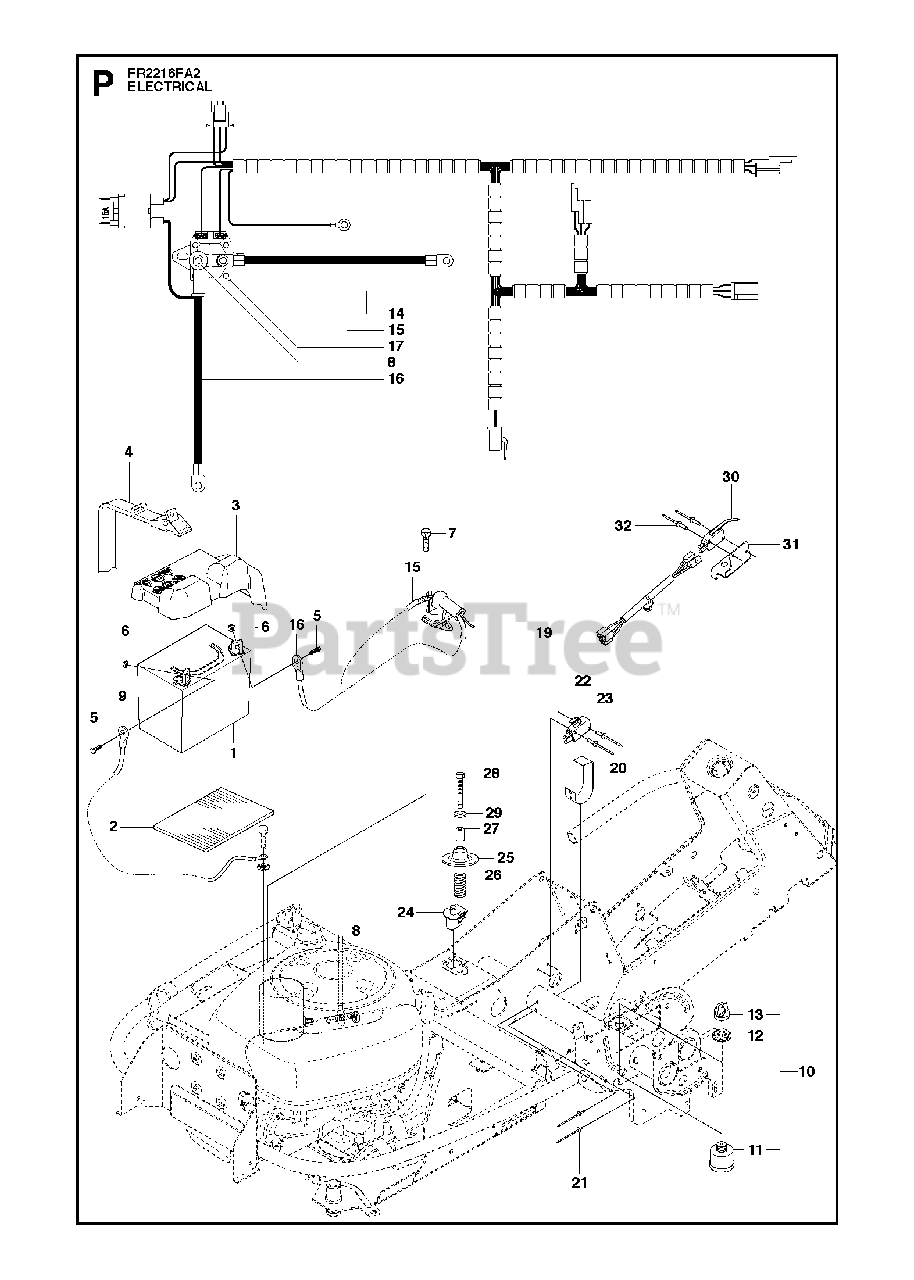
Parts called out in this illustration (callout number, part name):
5	SCREW EHHM
10	IGNITION SWITCH
11	IGNITION SWITCH
12	NUT
13	IGNITION KEY
19	WIRING
27	SPACER TUBE
28	SCREW
29	WASHER BRB 8.4X17
30	MICRO SWITCH
